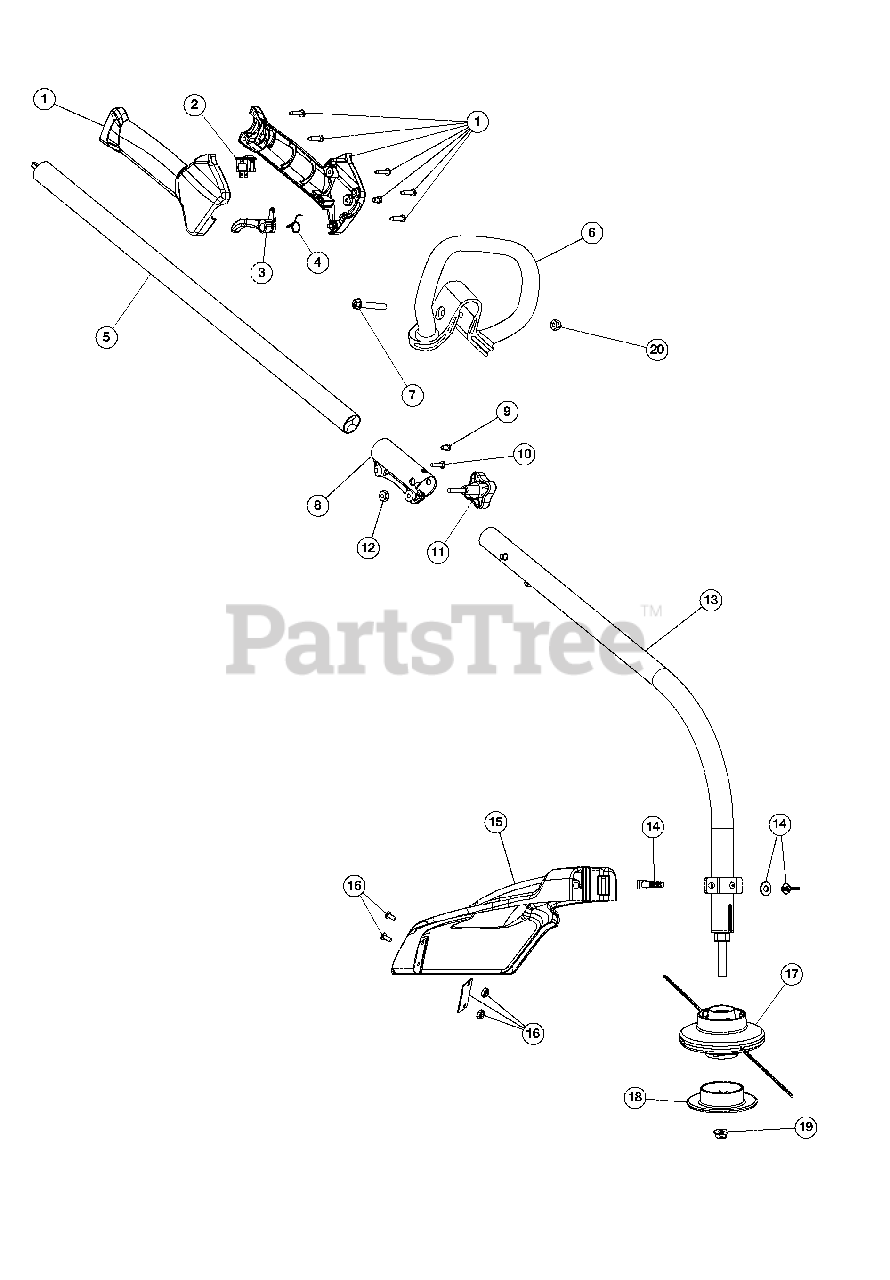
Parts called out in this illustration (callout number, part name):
1	Throttle Housing Assembly (Incl. 2-4)
3	Throttle Trigger
4	Throttle Trigger Spring
5	Upper Shaft Housing Assembly
6	D-Handle (Incl. 7)
7	D-Handle Hardware Assembly
8	Split Boom Coupler (Incl. 9-12)
9	Anti-Rotation Screw
11	Adjustment Knob
12	Knob Retainer Nut
13	Lower Shaft Housing Assembly
14	Shield Mounting Hardware
15	Shield Assembly (Incl. 16)
16	Blade Assembly
17	Cutting Head Assembly (Incl. 18 & 19)
18	Glide Cap
19	Lock Nut
